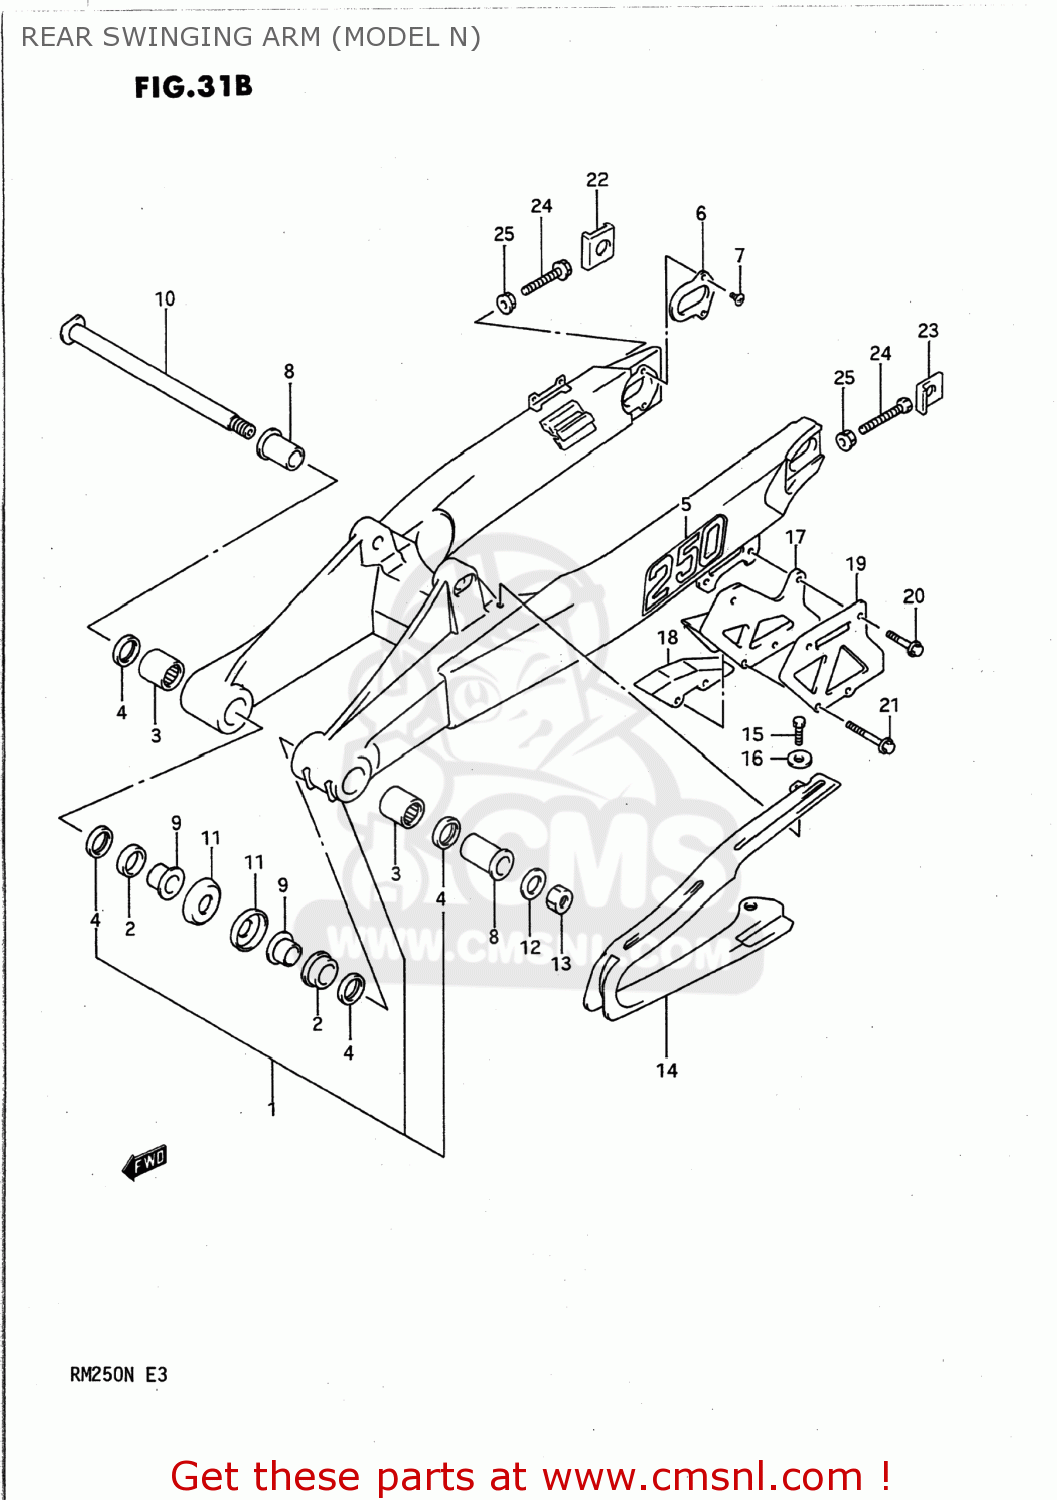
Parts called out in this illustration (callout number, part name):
1	SWING ARM ASSEMBLY,REAR
2	BUSHING,SWGARM PIVOT
3	BEARING(22X29X30)
4	SEAL,OIL(22X29X4)
5	EMBLEM,SWINGINGARM
6	PLATE,SWING ARM,REAR
7	SCREW
8	SPACER,REAR SWING ARM
9	SPACER,SWGARM PIVOT INNER
10	SHAFT,RR SWINGINGARM PIVOT
11	COVER,SWINGINGARM PIVOT
12	WASHER
13	NUT
14	BUFFER,CHAIN TOUCH DEFENSE
15	BOLT
16	WASHER
17	GUIDE,CHAIN
18	DEFENSE,CHAIN GUIDE
19	PLATE,CHAIN GUIDE,OUTER
20	BOLT
21	SCREW(6X40)
22	WASHER,CHAIN ADJUSTER
23	WASHER,CHAIN ADJUSTER,L
24	BOLT(8X50)
25	NUT
